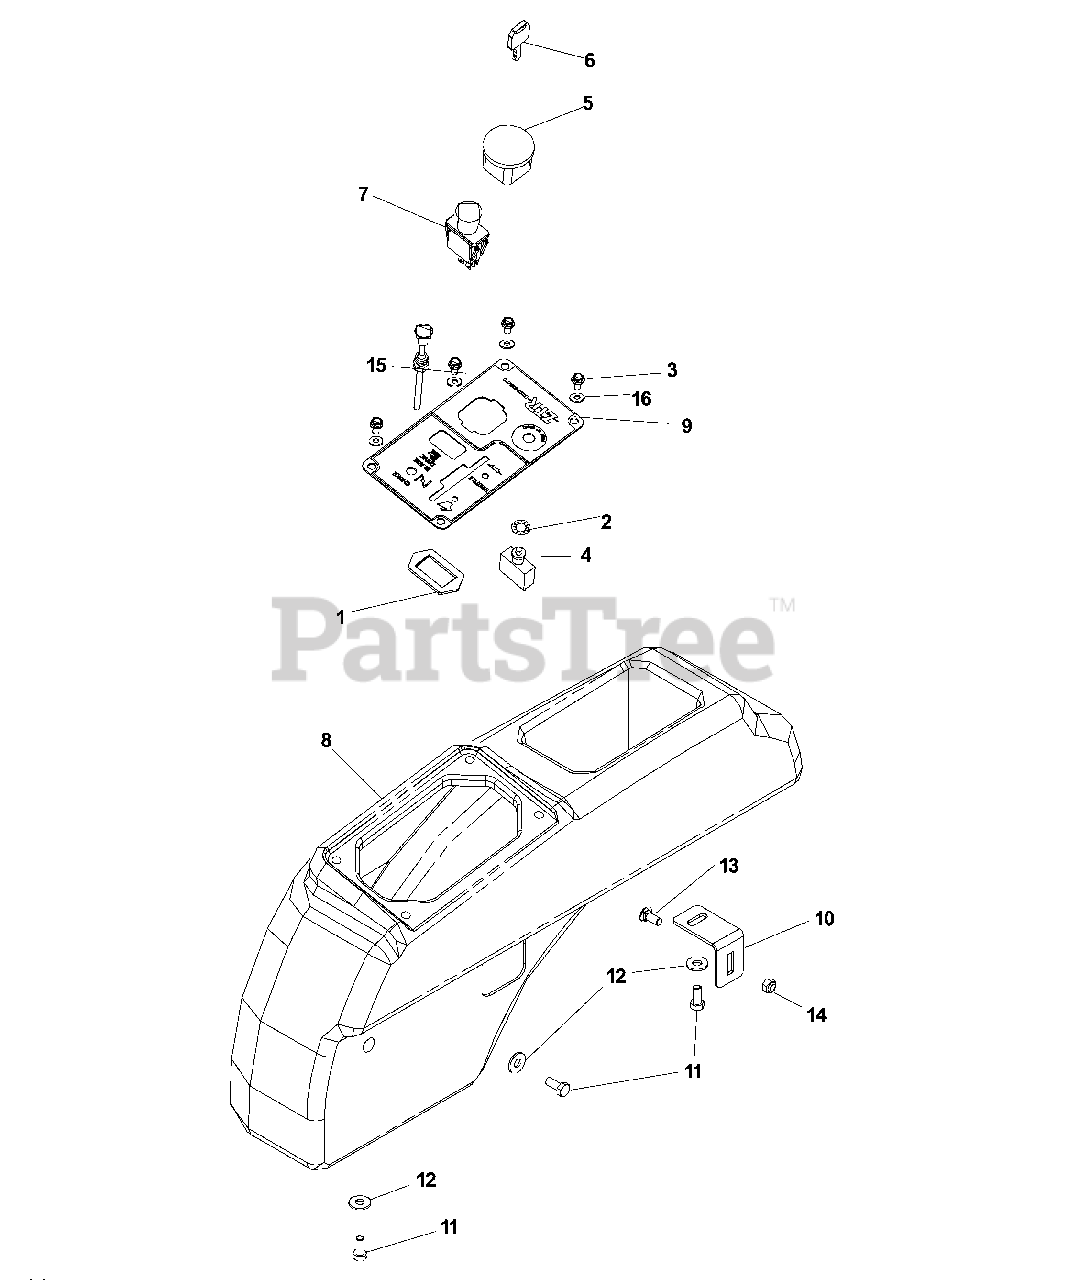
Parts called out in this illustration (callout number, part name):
1	PTO SWITCH RETAINER
2	7/16 INT TOOTH LWASH
3	SCREW 1/4 X 5/8
4	CIRCUIT BREAKER W58XB1A4A15
5	IGNITION SWITCH
6	KEY
7	SWITCH, BLADE
8	FENDER RH
9	CONTROL PANEL
10	TANK BRKT.
11	HCS 5/16C X 3/4
12	FLAT WASHER 5/16 SAE
13	BOLT 5/16C X 3/4" CARRIAGE
14	NUT 5/16 NYLOC
15	PUSH/PULL CHOKE CABLE
16	WASHER 1/4 FLAT
